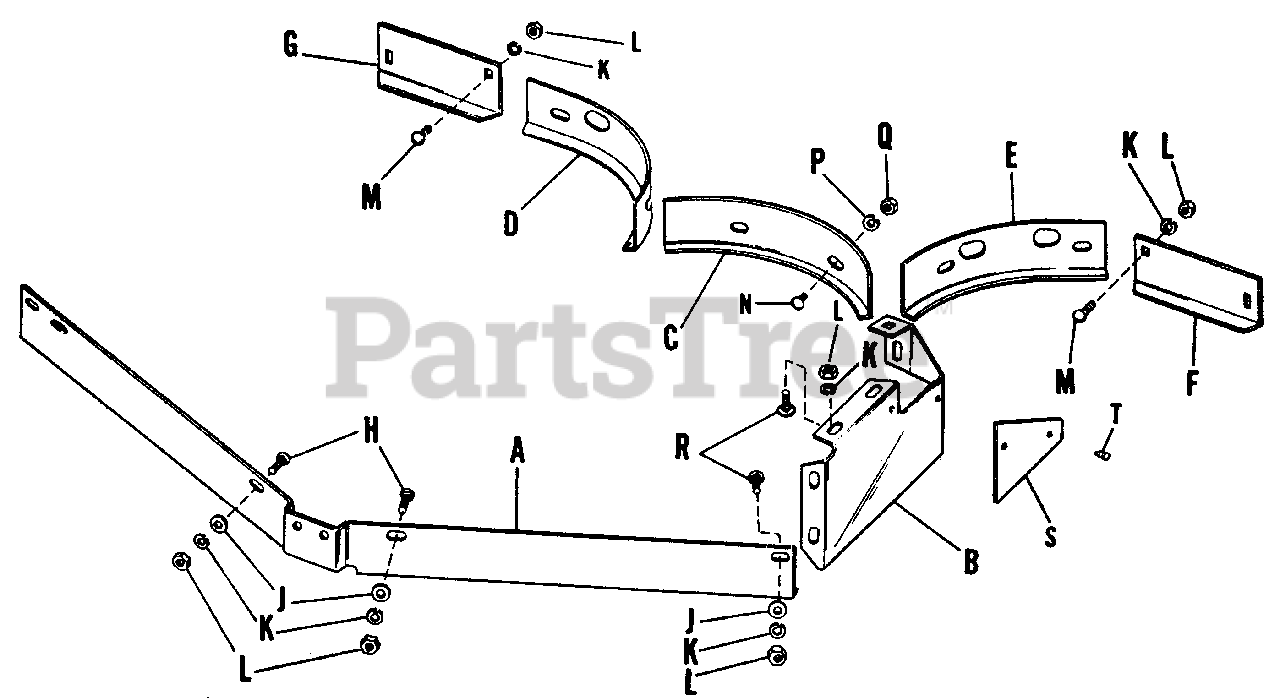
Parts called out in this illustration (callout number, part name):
A	Baffle Mulcher, Front
B	Plate-End-Housing
C	Baffle, Mulcher, Rear Center
D	Baffle, Mulcher, Right Hand Side
E	Baffle, Mulcher, Left Hand Side
F	Baffle, Left Hand, Rear
G	Baffle, Right Hand, Rear
H	Carriage Bolt, 3/8"-16 NC x 3/4" w/short square neck
J	Washer, Plain, 3/8" Std.
K	Washer, Lock, 3/8"
L	Nut, Hex, Full, 3/8"-16
M	Carriage Bolt, 3/8"-16 x 1"
N	Carriage Bolt, 5/16"-18 NC x 3/4" w/short square neck
P	Washer, Lock, 5/16"
Q	Nut, Hex, Full, 5/16"-18
R	Carriage Bolt, 3/8"-16 x 3/4"
T	Screw, Rec. Hex. Hd. Self Tapping, 1/4"-20 x 3/8"
